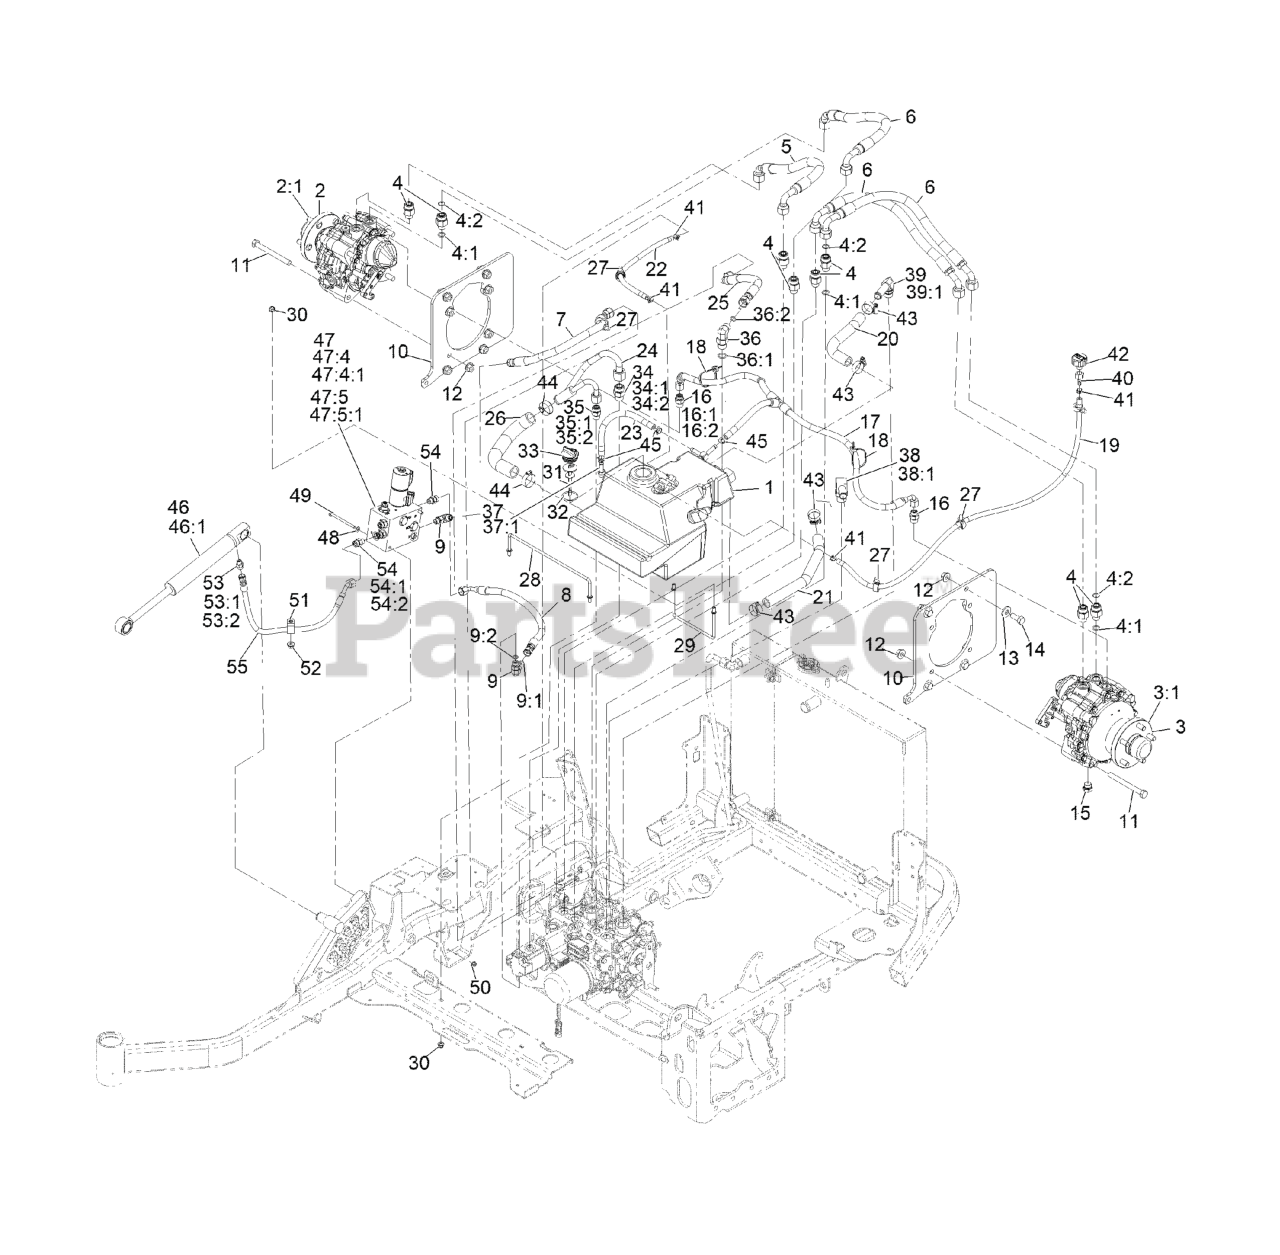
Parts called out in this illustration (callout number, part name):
1	HYD RESERVOIR ASM
2	MOTOR-HYD, RH
2:1	5 STUD WHEEL HUB KIT
3	MOTOR-HYD, LH
3:1	5 STUD WHEEL HUB KIT
4	FITTING-STRAIGHT
4:1	O-RING
5	HOSE ASM
6	HOSE ASM
7	HOSE ASM
8	HOSE ASM
9	FITTING-ELBOW, 90 DEG
9:1	O-RING
9:2	O-RING
10	PLATE-MOTOR
11	SCREW-HH
12	NUT-HHF
13	WASHER-SPRING
14	SCREW-HH
15	PLUG-MAGNETIC
16	FITTING-STRAIGHT
16:1	O-RING
16:2	O-RING
17	TEE HOSE ASM
18	TIE-CABLE
20	HOSE-RETURN
21	HOSE-RETURN
24	TUBE ASM
25	HOSE ASM
26	HOSE-SUCTION
27	CLIP-TIE
28	ROD-SUPPORT, HYD TANK
29	ROD-SUPPORT, HYD TANK
30	NUT-HF, NI
31	DIPSTICK
33	PLUG-PLASTIC
34	FITTING-STRAIGHT
34:1	O-RING
34:2	O-RING
35	FITTING-STRAIGHT
35:1	O-RING
35:2	O-RING
36	FITTING-ELBOW, 90 DEG
36:1	O-RING
36:2	O-RING
37	ADAPTER-STRAIGHT
37:1	O-RING
38	FITTING-ELBOW, 90
38:1	O-RING
39	FITTING-90
39:1	O-RING
40	FITTING-STRAIGHT
41	CLAMP-HOSE
42	BREATHER
43	CLAMP-HOSE
44	CLAMP-HOSE
45	CLAMP-HOSE
46	CYLINDER-LIFT
47	Valve-Lift And Hold
47:4	Solenoid Valve ASM
47:4:1	SPOOL VALVE SEAL KIT
47:5	Valve-Counterbalance
47:5:1	Seal Kit
48	WASHER-FLAT
49	SCREW-HH
51	CLIP-LOOM
52	NUT-HF, NI
53	FITTING-HYD, STRAIGHT
53:1	O-RING
53:2	O-RING
54	FITTING-STRAIGHT
54:1	O-RING
54:2	O-RING
55	HOSE ASM
